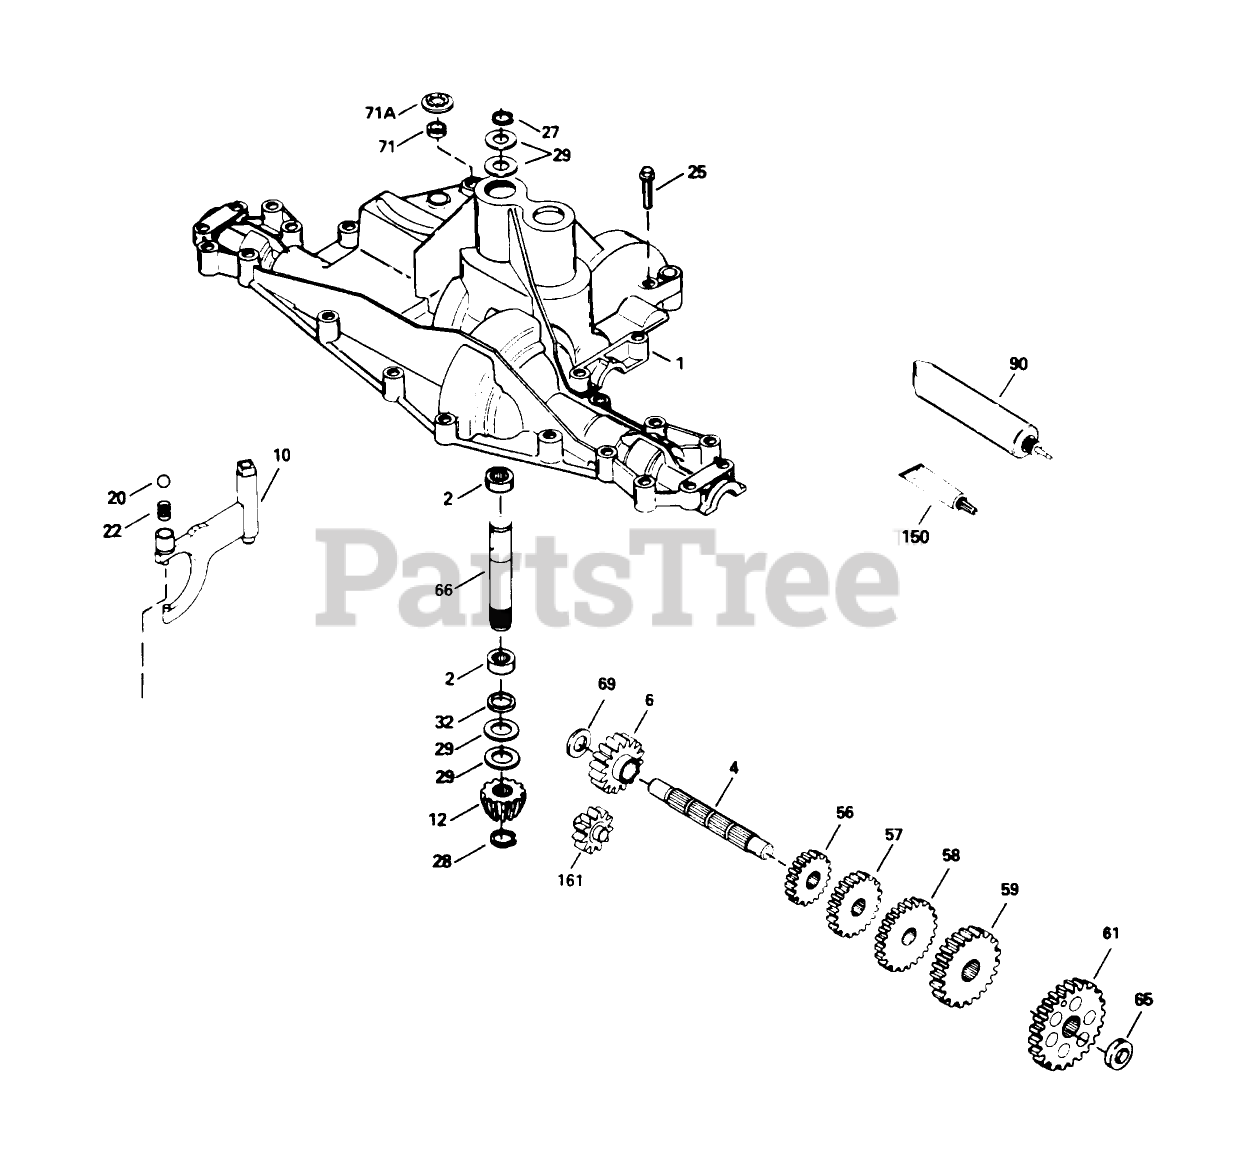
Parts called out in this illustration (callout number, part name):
1	Transaxle Cover
4	Countershaft
6	Spur Gear (16 Teeth)
10	Shift Rod Fork
12	Bevel Pinion (14 Teeth)
20	Ball (3/8" dia.)
22	Spring
25	Ring Set (.020 O S)
27	Ring-Snap
28	Ring-Retainer
29	Washer
32	O Ring
56	Gear-Spur, 15 Teeth
57	Gear-Spur 23 Teeth
58	Spur Gear (21 Teeth)
59	Gear-Spur (30 teeth)
61	Spur Gear (34Teeth)
65	Washer
66	Input Shaft (3.522" Ig.)
69	Thrust Washer
71	Cut Seal-Square
71A	Pushnut
90	Grease 32 Oz
150	Gasket Eliminator
161	Reverse Idler Assembly
